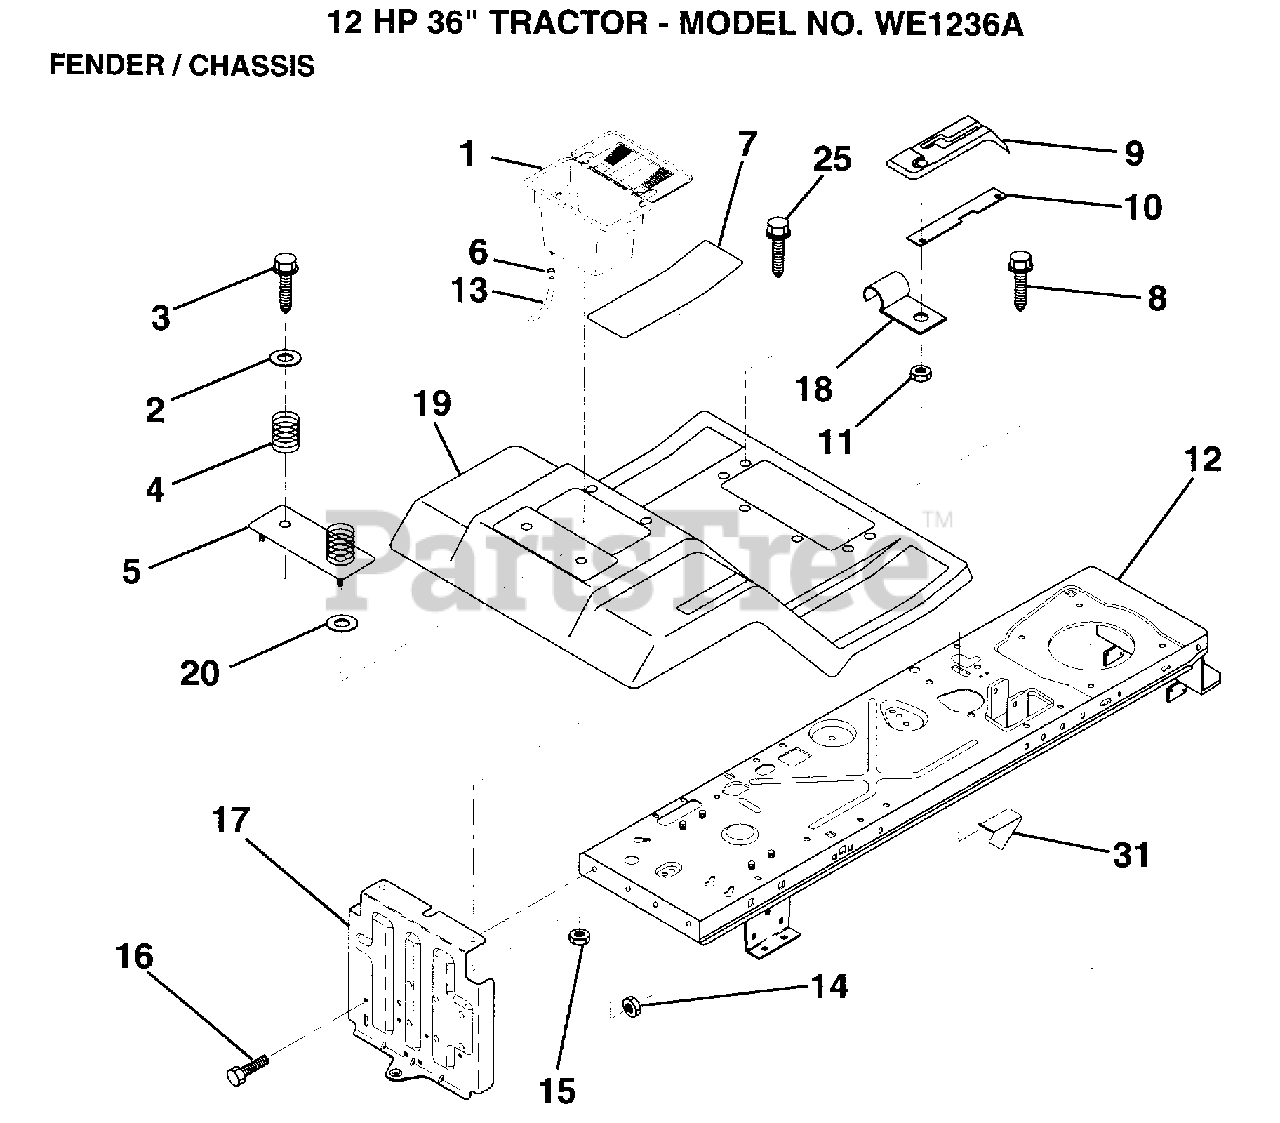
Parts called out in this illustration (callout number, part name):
2	WASHER
3	SCREW
4	SPRING COMPRESSIO
5	"PLATE, BATTERY"
6	HOSE CLAMP T
7	PAD FOOTREST
8	SCREW
10	PLATE LOCK SHIFT
11	NUT
13	TUBE T
14	NUT
15	NUT
16	BOLT
17	DRAWBAR ASM LR
18	"CLIP,INSULATOR"
19	FENDER/FOOT MS419
25	SCREW TI
